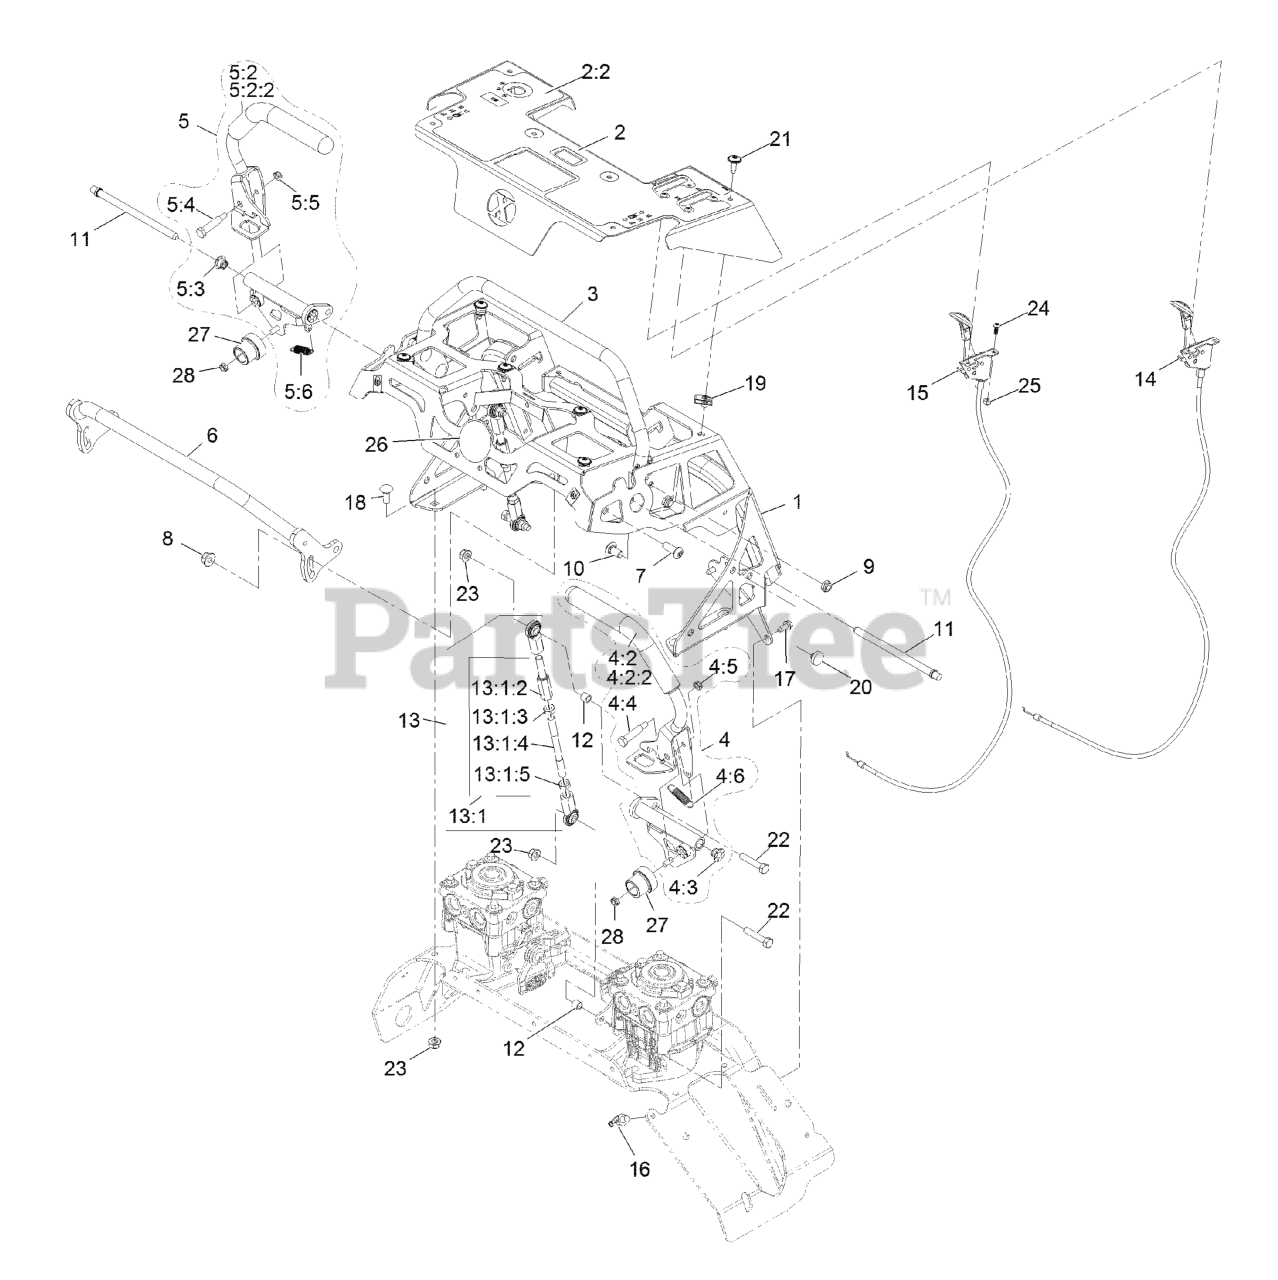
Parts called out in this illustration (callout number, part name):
1	ASM, Control Tower W/Decal
2	ASM,Control Panel W/Decal
2:2	Decal-Control Panel Non-EFI
3	Weld, Rear Ref Bar
4	ASM, Motion Control, Lt
4:2	ASM, Lt Control Lever W/ Grip
4:2:2	Grip, Drive Lever
4:3	Bearing, Igus
4:4	BOLT-SHOULDER
4:5	NUT-LOCK, NI
4:6	SPRING-EXTENSION
5	ASM, Motion Control, Rt
5:2	ASM, Rt Control Lever W/ Grip
5:2:2	Grip, Drive Lever
5:3	Bearing, Igus
5:4	BOLT-SHOULDER
5:5	NUT-LOCK, NI
5:6	SPRING-EXTENSION
6	Weld, Front Ref Bar
7	SCREW-HSBH
8	NUT-HF, NI
10	SCREW-CARR
11	PIN, PIVOT
13	ASM, Linkage
13:1	ASM, Motion Control Link
13:1:2	ROD-ADJUSTMENT
13:1:3	NUT-HEX JAM, LH
13:1:4	Link, Motion Control
13:1:5	NUT-HJ
14	CONTROL, CHOKE
15	CONTROL, THROTTLE
16	CLIP-TIE
17	SCREW-HWH
18	SCREW-CARR
21	Screw, Torx
22	SCREW-HH
23	NUT-HF, NI
24	SCREW, BHCS
25	NUT-LOCK, NI
26	Decal-Cover
28	NUT-LOCK, NI
